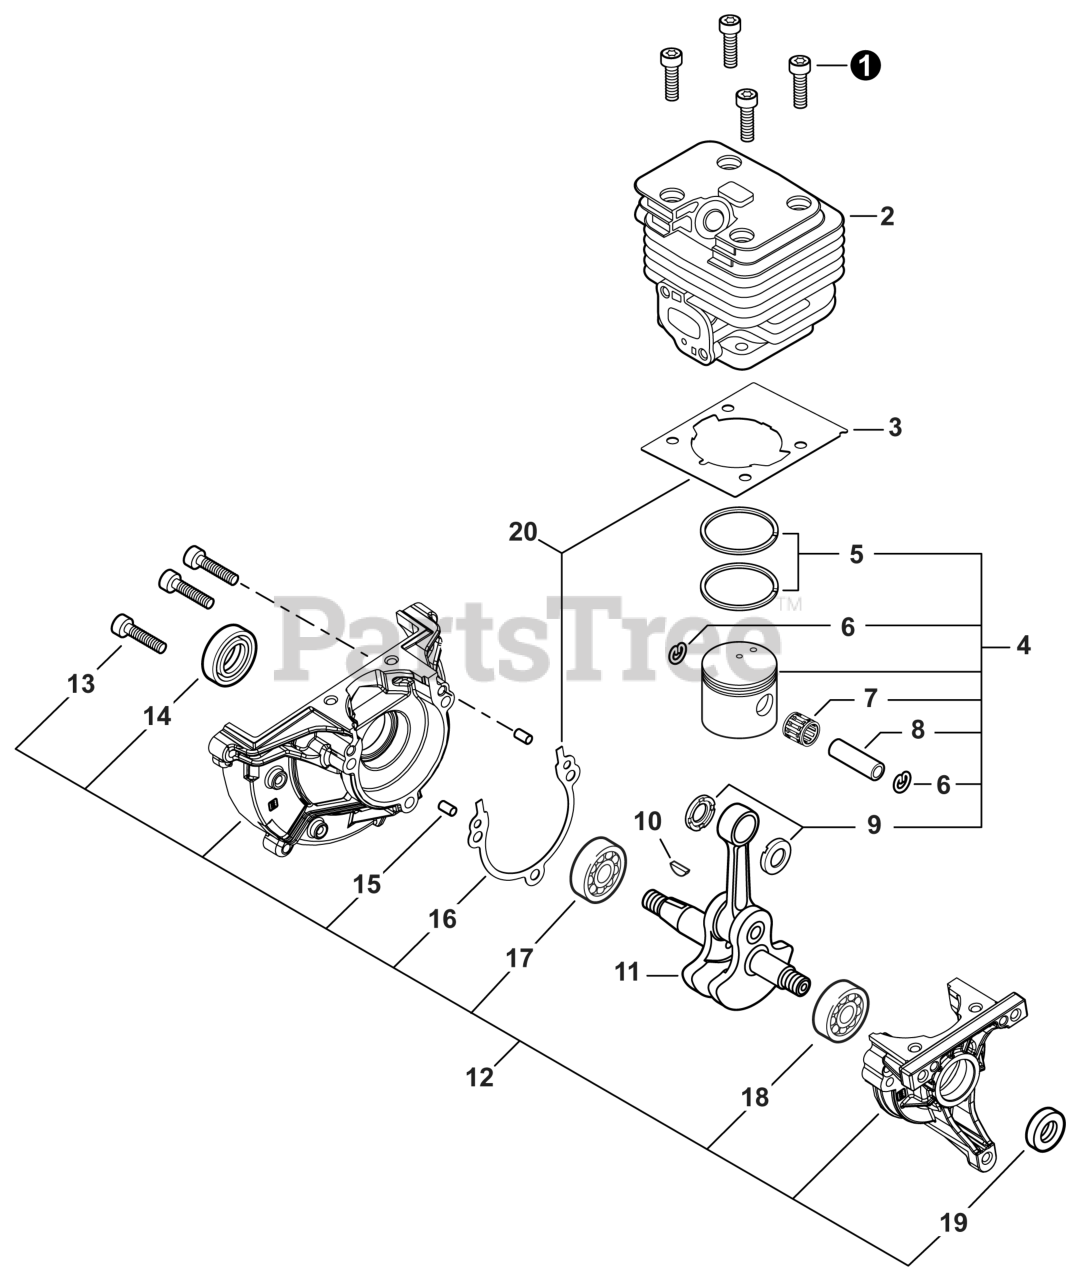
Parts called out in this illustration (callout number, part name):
1	BOLT, TORX 5x20
2	CYLINDER
3	GASKET, CYLINDER
4	PISTON KIT
5	RING, PISTON
6	RING, SNAP
7	BEARING, NEEDLE 9
8	PIN, PISTON
9	WASHER, THRUST
10	KEY, WOODRUFF
11	CRANKSHAFT ASSY
12	CRANKCASE ASSY
13	BOLT, TORX 5x25
14	SEAL, OIL 12
15	PIN, LOCATING 4x8
16	GASKET, CRANKCASE
17	BEARING, BALL
18	BEARING, BALL
19	SEAL, OIL 10
20	GASKET KIT: ENGINE, INTAKE, EXHAUST
